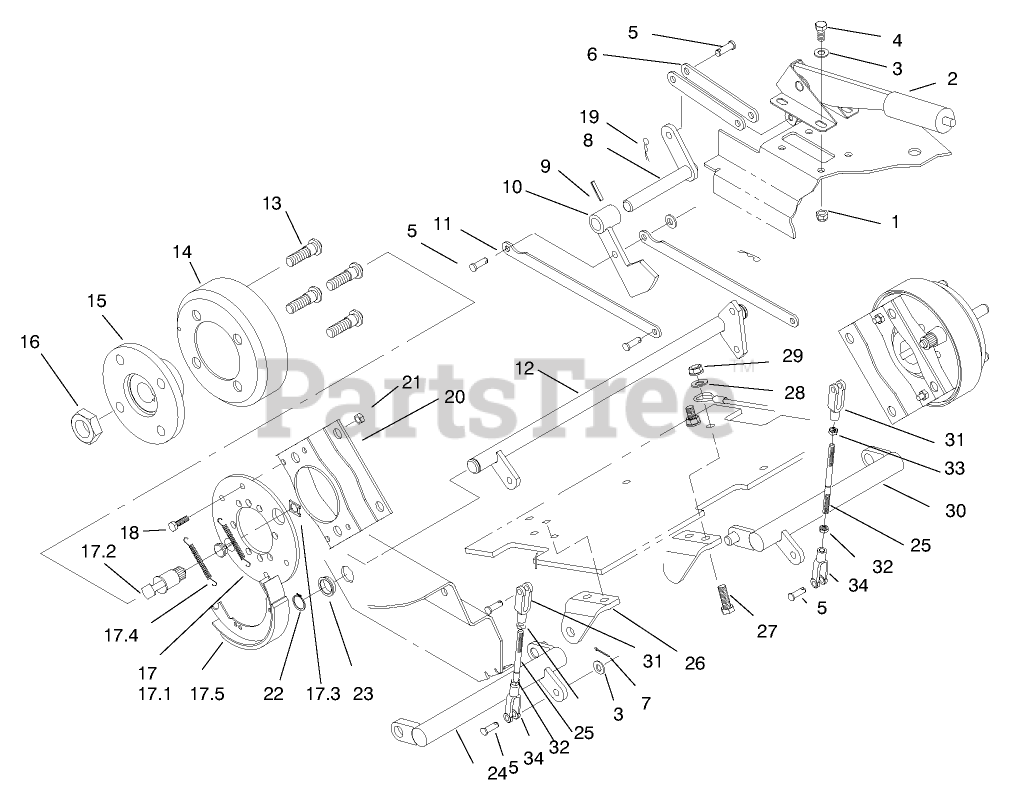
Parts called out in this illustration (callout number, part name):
1	NUT-LOCK, NI
2	LEVER-BRAKE
3	WASHER-PLAIN
4	SCREW-HH
5	PIN-CLEVIS
6	LINK-BRAKE
7	PIN-COTTER
8	TRANSFER SHAFT ASM
9	PIN-SPIRAL
10	BRAKE HUB ASM
11	LINK - CONNECT
12	TORSION SHAFT ASM
13	STUD-DRIVE
14	DRUM-BRAKE
15	Hub-Wheel
16	NUT-LOCK
17	BrakeASM
17:1	PLATE-BACKING
17:2	Cam Shaft
17:4	SPRING-RETURN
17:5	SHOE-BRAKE
18	SCREW-HH
19	PIN-COTTER
20	Bracket-Brake
21	NUT-LOCK, NI
22	Ring-Snap
23	BUSHING
24	RH BRAKE LEVER ASM
25	ROD-BRAKE
26	MOUNT-LEVER, BRAKE, RH
27	SCREW-HH
28	WASHER-FLAT
29	NUT-LOCK, NI
30	LH BRAKE LEVER ASM
31	YOKE
32	NUT-JAM
33	NUT-JAM
34	CLEVIS-ADJUSTABLE
